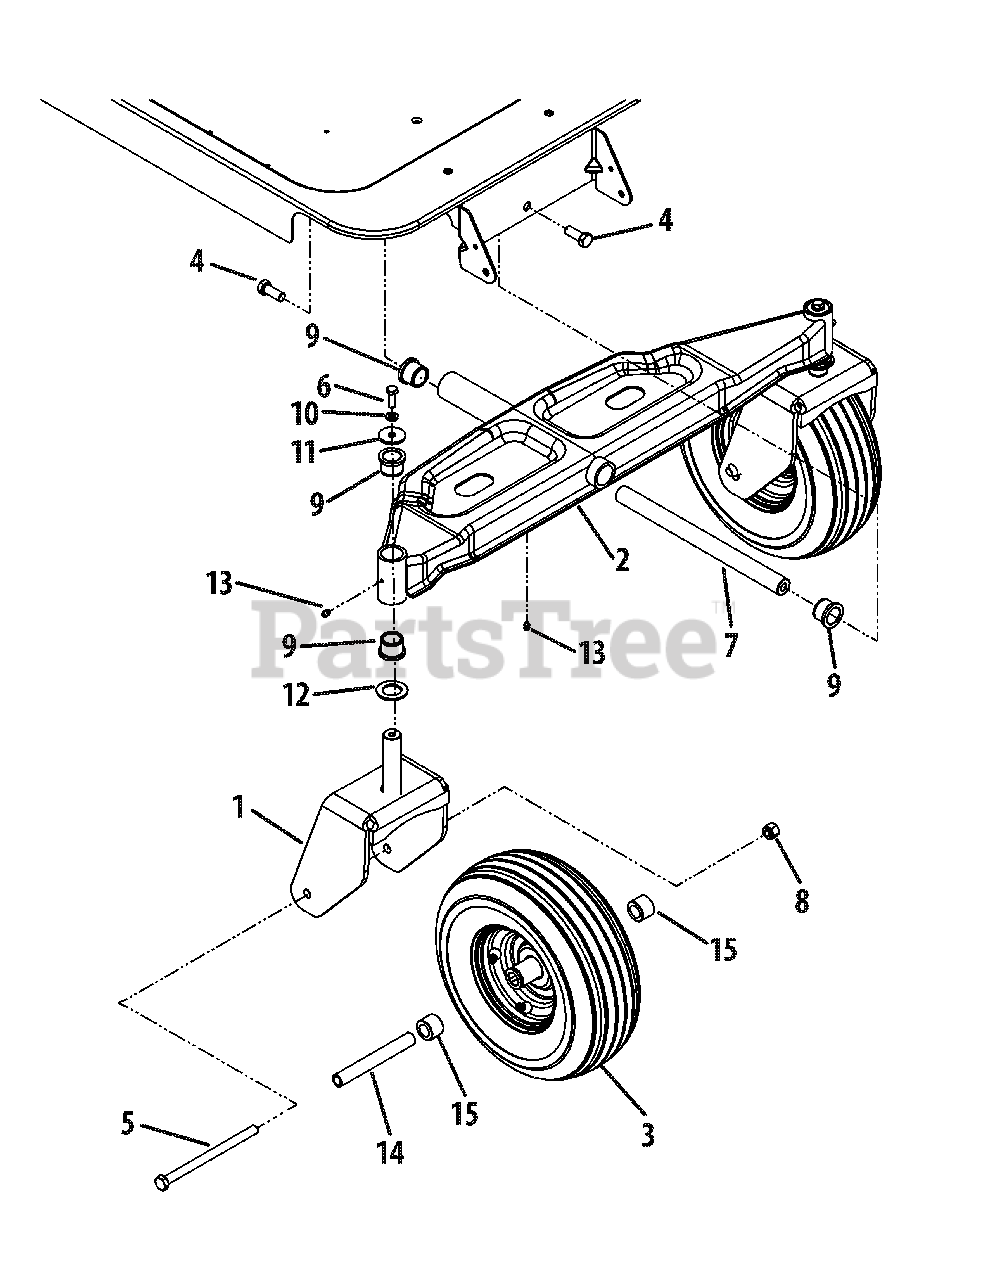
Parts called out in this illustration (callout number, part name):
1	Castor Wheel Bracket - Green
1	Castor Wheel Bracket - Black Jack
2	Front Pivot Axle - Green
2	Front Pivot Axle - Black Jack
3	Wheel Assembly, 13 x 5-6
4	Hex Lock Screw, 1/2-13 x 1.25
5	Hex Cap Screw, 1/2-20 x 7.25
6	Hex Cap Screw, 3/8-16 x 1.0
7	Axle Shaft
8	Hex Insert Lock Nut, 1/2-13
9	Flange Bearing, 1.0 x 1.246
10	Lock Washer, 3/8
11	Flat Washer, .39 x 1.5 x .134
12	Flat Washer, 1.0 x 1.75 x .10
13	Lube Fitting, 3/16 Drive
14	Spacer, .51 x .75 x 5.825
15	Hub, .76 x 1.23 x .92
